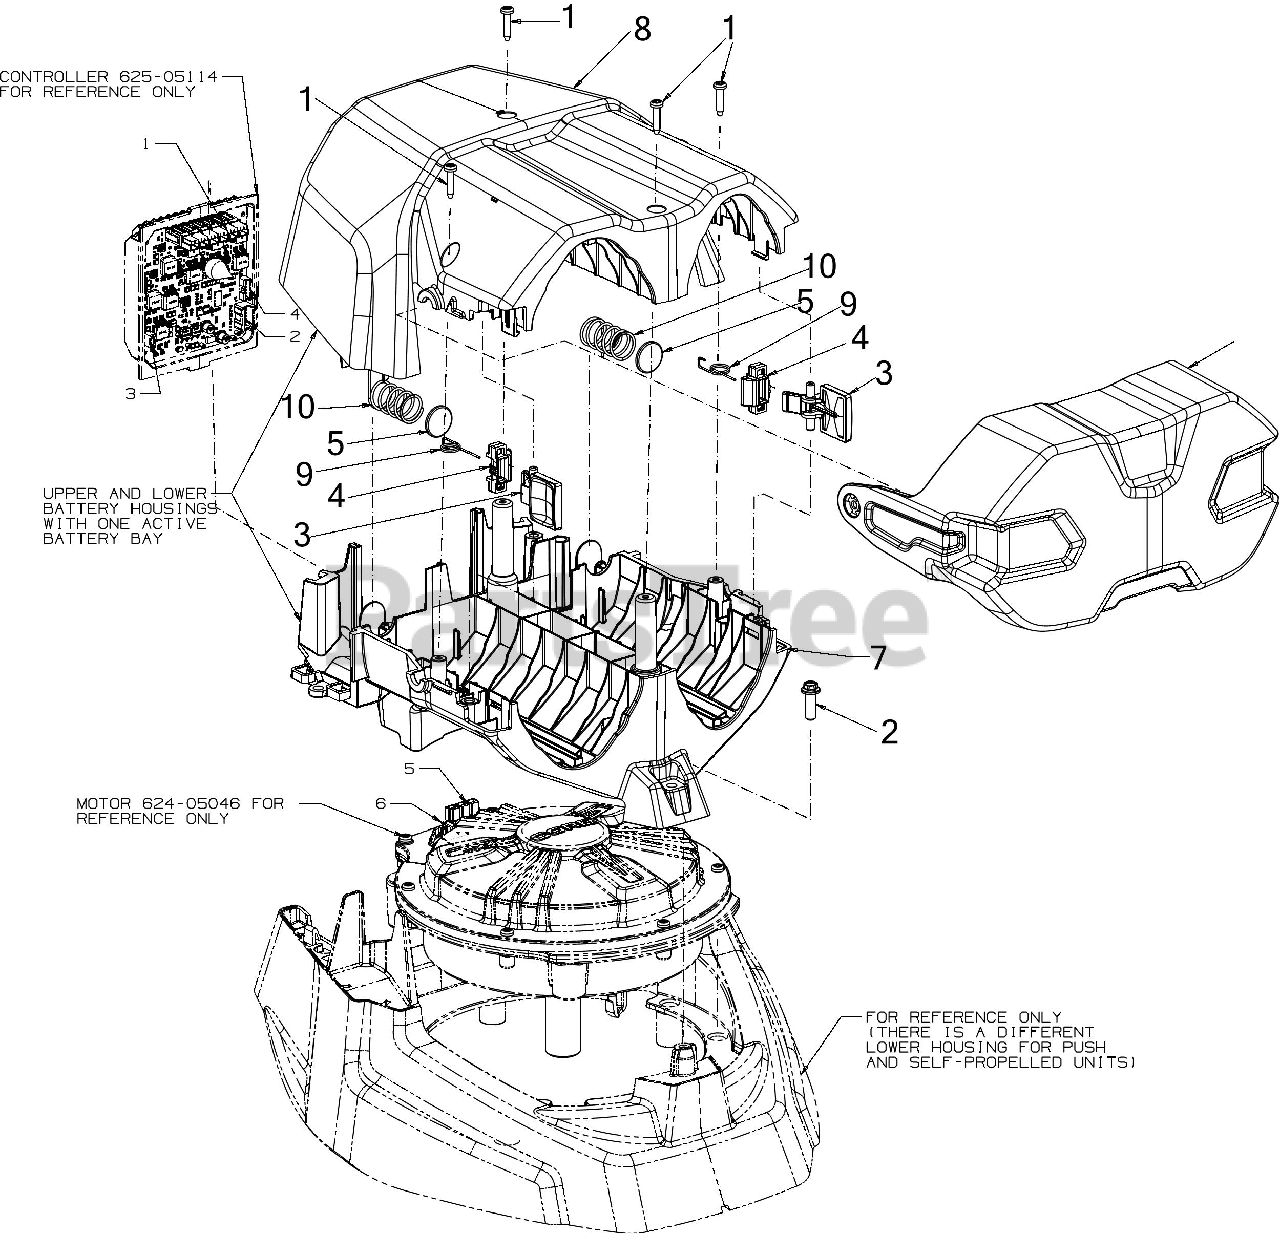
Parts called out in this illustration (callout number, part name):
1	SCREW 7-18X.75:T20
2	SCREW 1/4 x .750
3	BATTERY RELEASE BUTTON
4	BATTERY RELEASE LATCH
5	BATTERY RELEASE SPRING CAP
6	BATTERY HOUSING LID
7	MIDDLE BATTERY HOUSING
8	SINGLE BATTERY UPPER HOUSING
9	TRIGGER SPRING
10	BATTERY RELEASE SPRING
